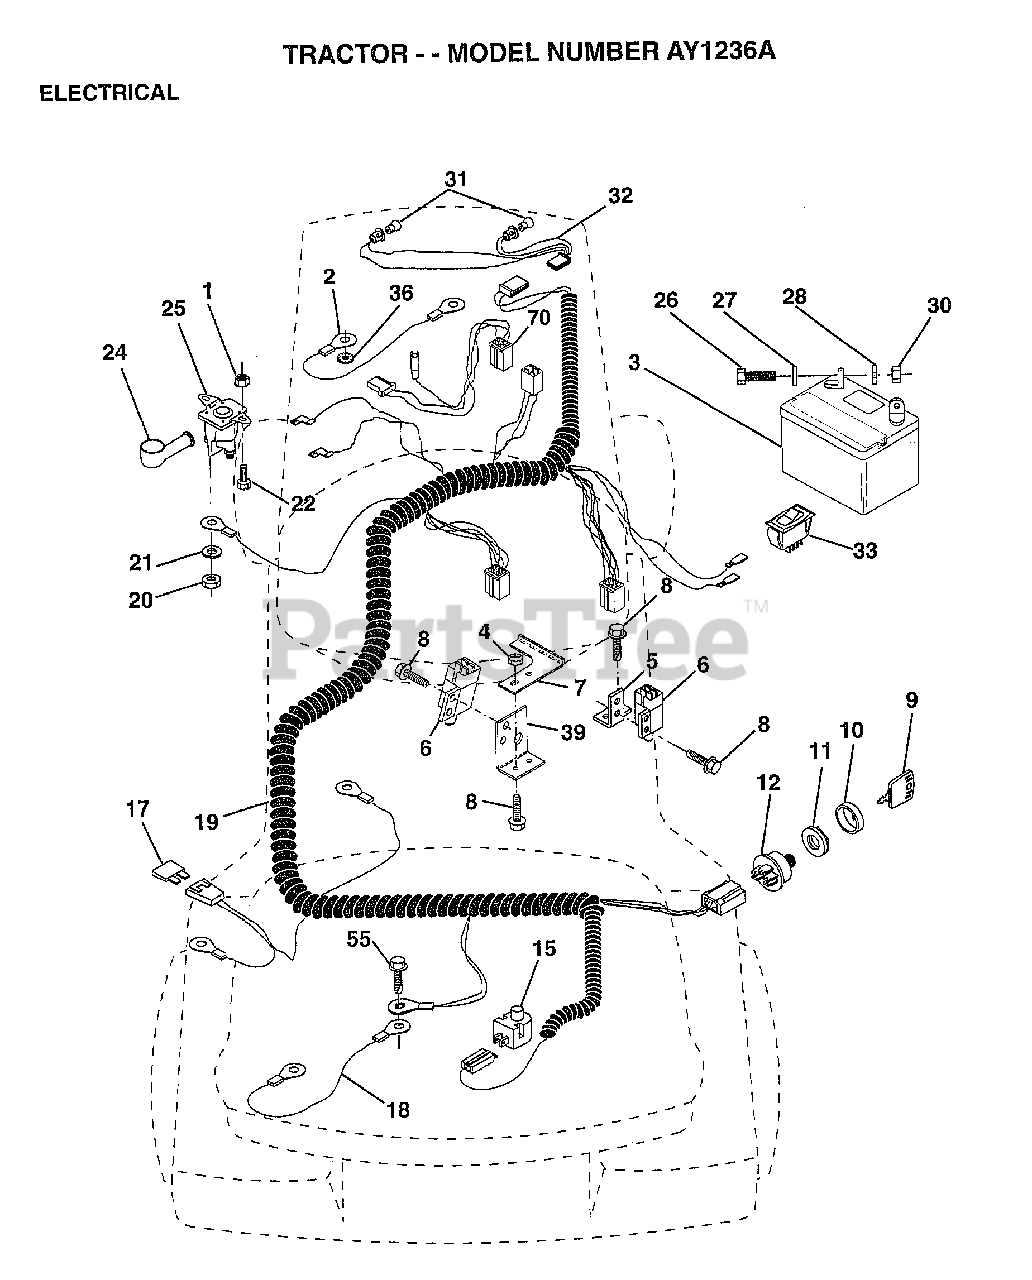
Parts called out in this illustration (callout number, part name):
1	NUT HXKEP 1/4X20
2	CABLE ASM.
4	LOCKNUT
5	BRACKET LT
6	SWITCH INTERLOCKT
7	KEEPER.ACTUAT.LR.
8	SCREW
9	KEY MLD GEN DELTA
10	COVER KEY SWITCH
15	SWITCH SEAT
17	FUSE HYT
18	CABLE ASSY
19	HARNESS.IGN.LR.
20	NUT
22	BOLT HXHD FIN
26	BOLT LT
27	WASHER
28	LOCKWASHER
31	HEADLAMP BULB
32	"HARNESS,LIGHT SOC"
33	SWITCH LT
36	LOCKWASHER
39	BRACKET SWT CLUTC
55	SCREW LT
70	HARNESS ENG DUAL
